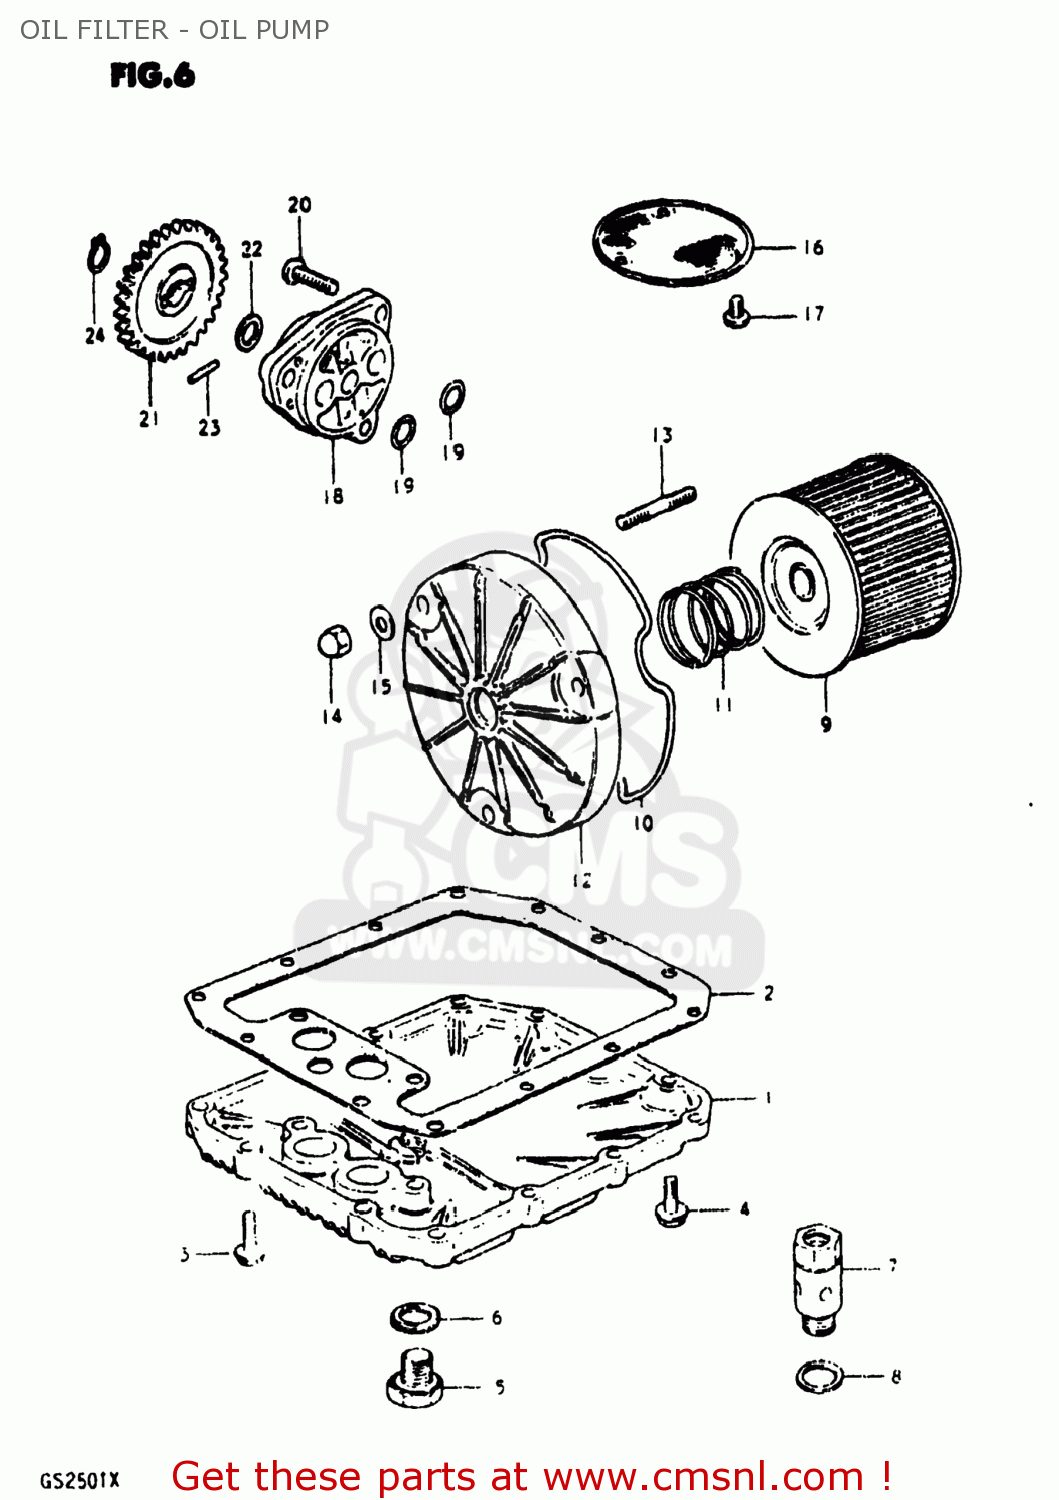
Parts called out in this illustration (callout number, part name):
1	PAN,OIL
2	GASKET,OIL PAN (MCA)
3	BOLT
4	BOLT,REAR
5	PLUG
6	GASKET(14X19.2X2) (NAS)
7	REGULATOR ASSEMBLY,ENGINE
8	WASHER
9	FILTER ASSY,ENGINE OIL
10	O RING,OIL FILTER CHAMBER CAP
11	SPRING
12	CAP,OIL FILTER
13	STUD 6X20
14	NUT
15	WASHER
16	STRAINER,ENGINE OIL
17	SCREW 6X12
18	PUMP ASSY,ENGINE OIL
19	O RING(D:1.9,ID:13)
20	SCREW
21	GEAR,OIL PUMP DRIVEN
22	SHIM
23	PIN(4X15.8)
24	CIRCLIP
